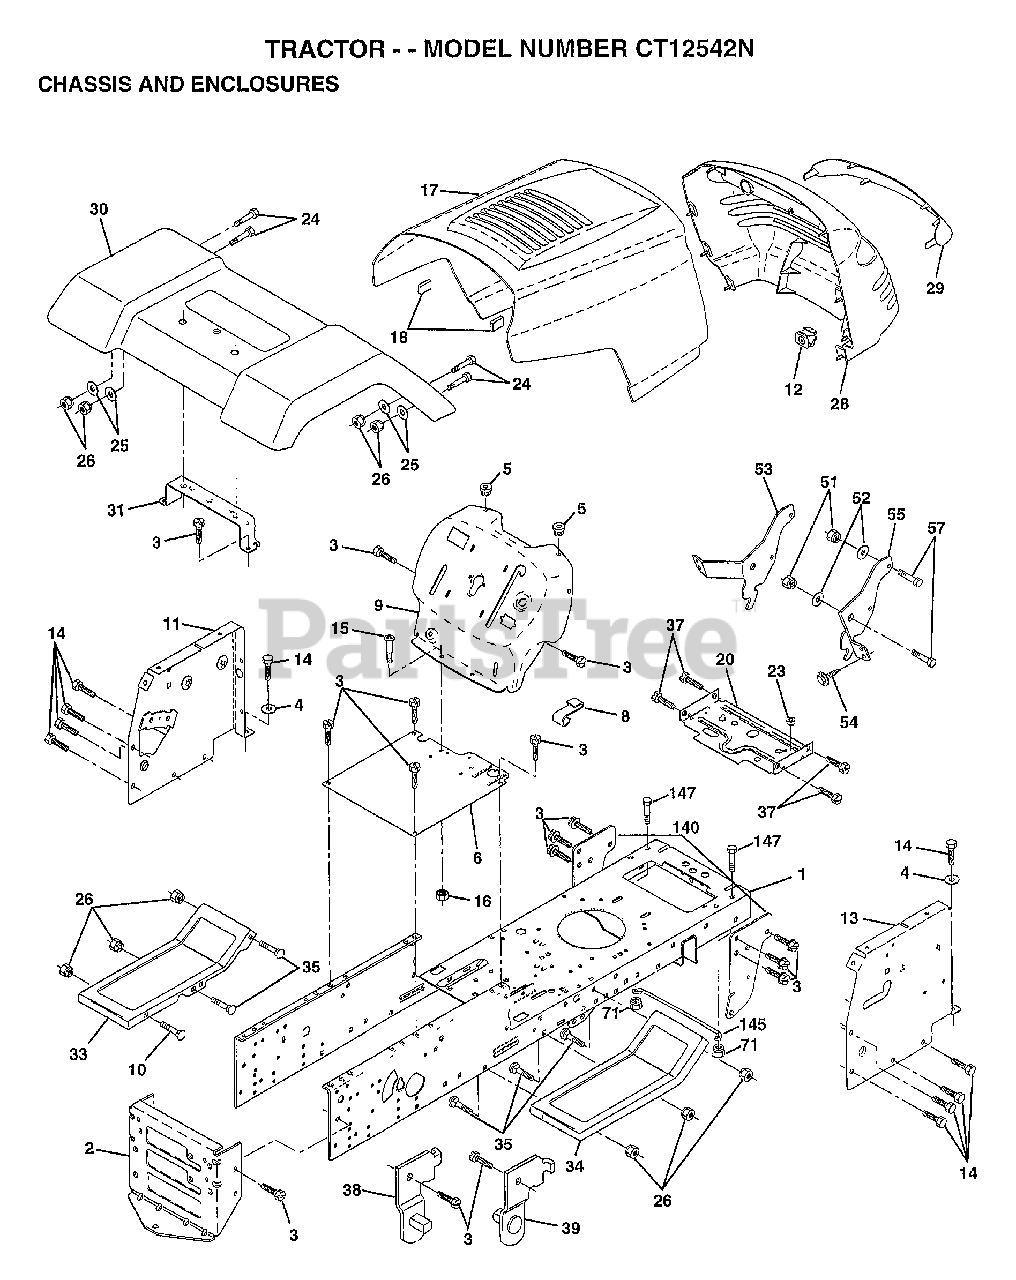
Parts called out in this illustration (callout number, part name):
1	CHASSIS ASM
3	SCREW
4	WASHER
5	BUMPER-HOOD/DASH
6	SADDLE-SILKSCREEN
8	CLIP.RETAINER
9	DASH.SILKSCREENED
11	"PANEL-DASH,LH"
12	CLIP.TINNERMAN
14	SCREW LT
15	SCREW
17	HOOD.STEEL.ASSY
20	"PLATE-MTG,BATT/FU"
24	BOLT
25	WASHER
26	NUT
28	GRILLE-MS428
29	LENS GRILLE
31	BRKT FENDER
33	FOOTREST.LH.PERF.
34	FOOTREST.RH.PERF.
35	BOLT
37	SCREW LT
38	BRACKET ASM LH
39	BRACKET ASM RH
51	NUT
52	WASHER
53	BRACKET.GRILLE.LH
55	BRACKET.GRILLE.RH
58	AIR DUCT
140	BRKT SUSPENSION
145	"ROD POVOT,CHASSIS"
147	BOLT LT
